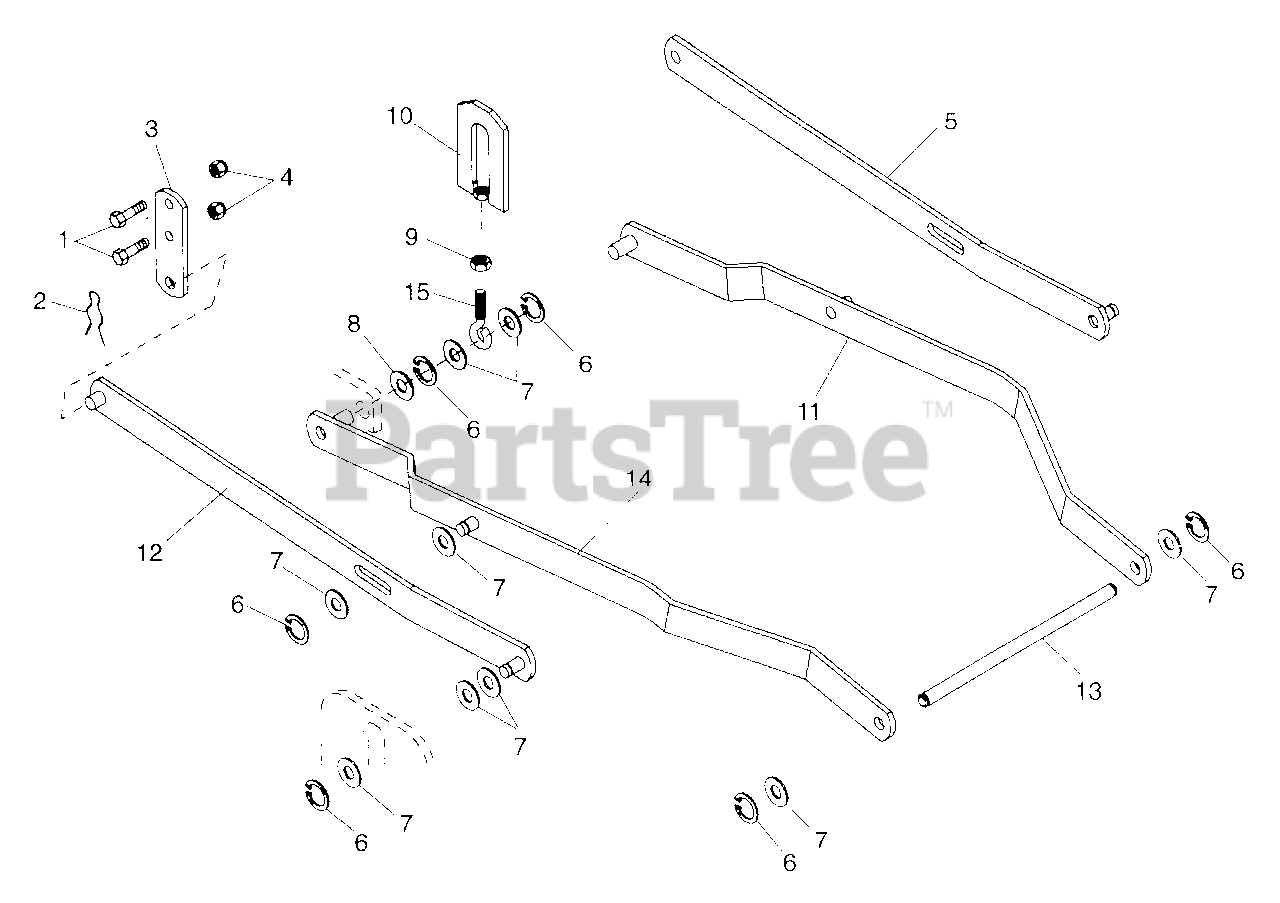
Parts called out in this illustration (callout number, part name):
1	BLT-HEX .38-16X.75 PL GR5
2	PIN-HAIR-EXT .062X.38X1.00
3	HANGER BRACKET
4	NUT-LK TOP .375-16 GR C YWZC
5	REAR HANGER LH
6	RG-RTNG-EXT .500X.050 (SNAP)
7	WSHR-FL-STL .531X1.062X.095 PL
8	WSHR-FL-STL .531X1.250X.100 PL
9	NUT-JAM .375-16 PL
10	LINK, ADJUSTMENT
11	LH LIFT ARM
12	REAR HANGER RH
13	PIN
14	RH LIFT ARM
